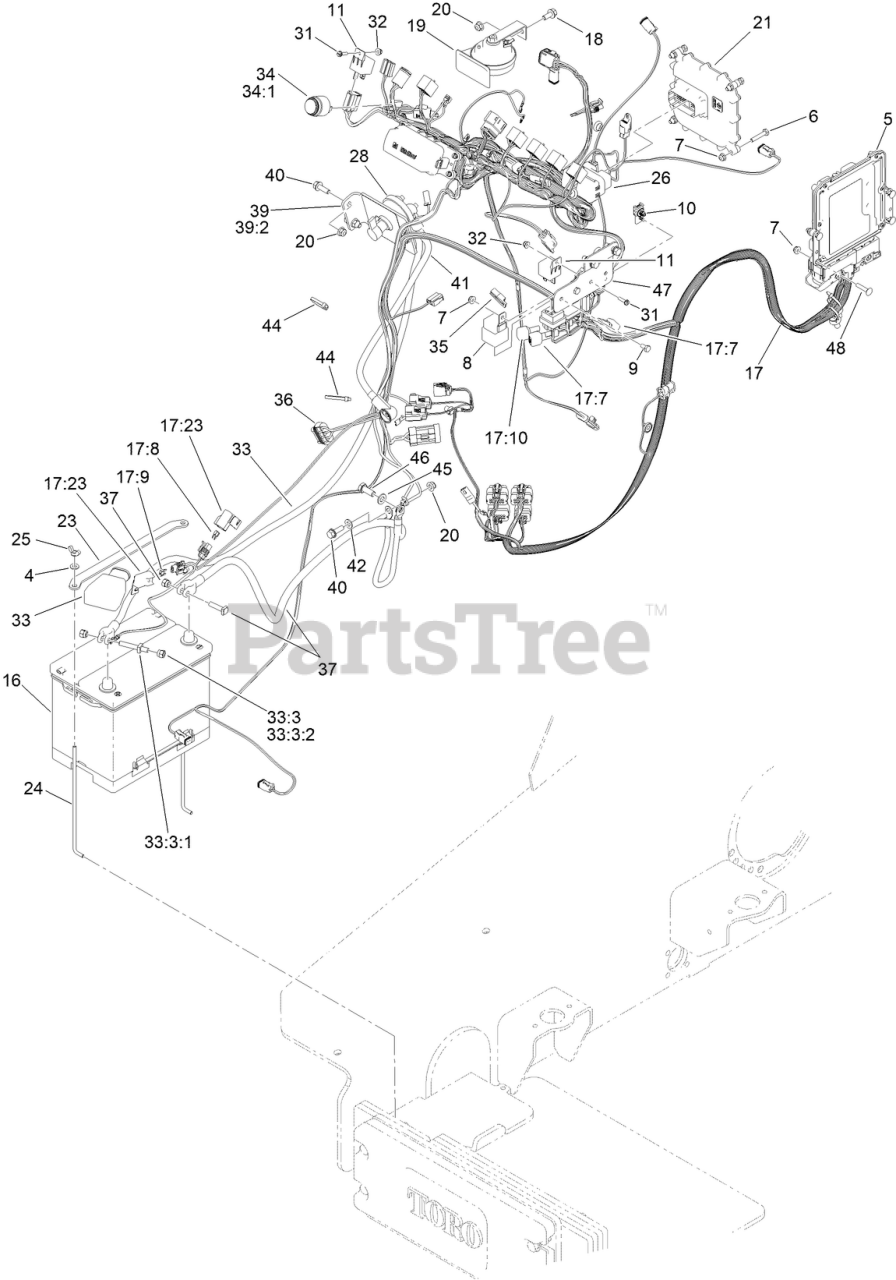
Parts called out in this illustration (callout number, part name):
4	WASHER-FLAT
5	CONTROLLER-ENGINE
6	SCREW-HH
7	NUT-HF
8	RELAY-MINI
9	SCREW-HH
10	CLIP-CONNECTOR
11	RELAY
17	HARNESS-WIRE, ENGINE T4
17:8	FUSE-MINI BLADE, 2 AMP
17:9	FUSE-MINI BLADE, 10 AMP
17:10	RESISTOR-75 OHM
17:23	COVER-FUSE, SINGLE
18	SCREW-HHF
19	Horn And Bracket Assembly (Inc. Ref.# 44 45)
20	NUT-HF, NI
21	CONTROLLER
23	STRAP-HOLD DOWN, BATTERY
24	ROD-HOLD DOWN, BATTERY
25	NUT-WING
26	HARNESS-WIRE, TX1300
28	SWITCH-DISCONNECT, MASTER
31	SCREW-HWH
32	NUT-HF
33	CABLE-BATTERY, RD ASM
33:3	BOLT ASM
33:3:1	BOLT-CLAMP, BATTERY
33:3:2	NUT-CLAMP, BATTERY
34	AUDIO ALARM ASM
34:1	NUT-PLASTIC, KNURLED
35	HARNESS-WIRE, FUSIBLE LINK
36	HARNESS-WIRE, FUSIBLE LINK
37	CABLE-BATTERY, NEGATIVE
39	BRACKET-SHUTOFF
39:2	DECAL-BATTERY DISCONNECT
40	SCREW-HHF
41	CABLE-BATTERY, RD ASM
42	WASHER-PLAIN
44	TIE-CABLE
45	WASHER-FLAT
46	SCREW-HH
47	BRACKET-RELAYS
48	SCREW-CARR
